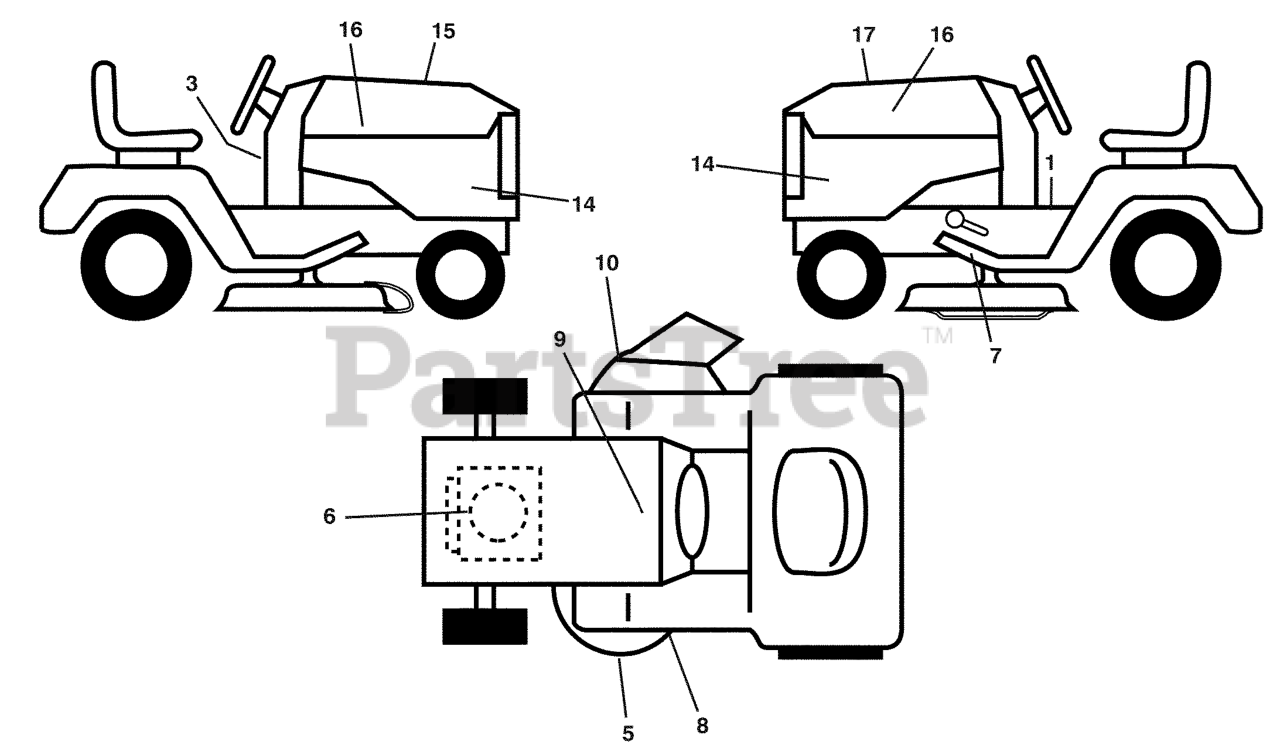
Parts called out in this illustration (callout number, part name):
1	DECAL.FENDER.WARNING.ENG
3	DECAL, WARNING SPARK ARRESTOR
5	DECAL.DECK.AIR.INDUCTION.HUSQ
6	DECAL.ENG.BSM44.23.ENDUR.27817
7	DECAL.PEDAL.HUSQ.CROWN
8	DECAL.MOWER.SCH.48/54
9	DECAL BTRY SYMBOLS
10	DECAL.WARN.KEEP.HAND.AWAY
14	DECAL.SDPNL.2348LS.ENDUR.HUSQ
15	DECAL.WARNING.CUST.RESP.E85.
16	RP EMBLEM, HOOD
17	DECAL.RPL.2348LS.2009
